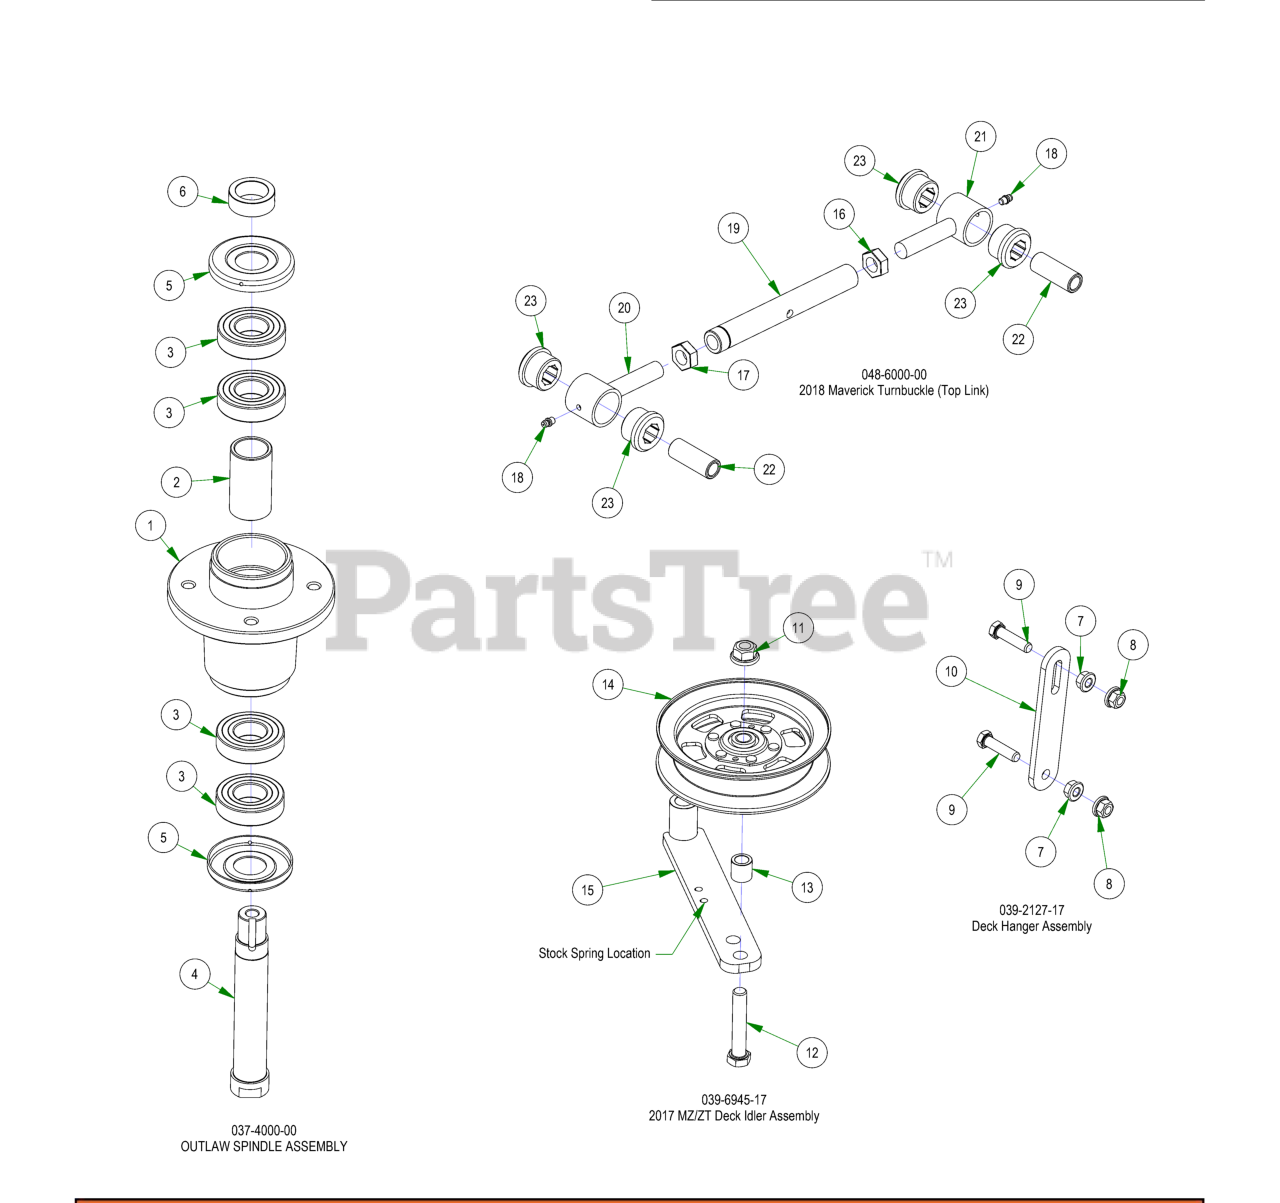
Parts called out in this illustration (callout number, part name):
1	4000 Series Spindle Housing
2	4000 Series Spindle Spacer
3	Bearing - 6206
4	Spindle Shaft
5	Spindle Dust Cap
6	Locking Collar w/ 1/4"-20 Set Screw
7	3/8-16 HEX SERRATED FLANGE NUT HARD/ZINC
8	3/8-16 NYLON INSERT FLANGE LOCKNUT (GR.F) ZINC
9	3/8-16 X 1-1/2 HEX CAP SCREW (GR.5) ZINC
10	2017 MZ/ZT Deck Hanger
11	1/2-13 NYLON INSERT FLANGE LOCKNUT ZINC
12	1/2-13 X 2-3/4 HEX CAP SCREW (GR.5) ZINC
13	Spacer 3/4 OD x 1/2 ID x 3\4 Length
14	5" Idler Pully
15	Deck Idler
16	NUT, 5/8-18
17	NUT, 5/8-18LH
18	1/4-28 Grease Fitting
19	2018 Maverick Toplink Body
20	2018 Maverick Bushing Retainer Left-Handed
21	2018 Maverick Bushing Retainer Right-Handed
22	2018 Maverick Bushing Sleeve
23	2018 Maverick Bushing
